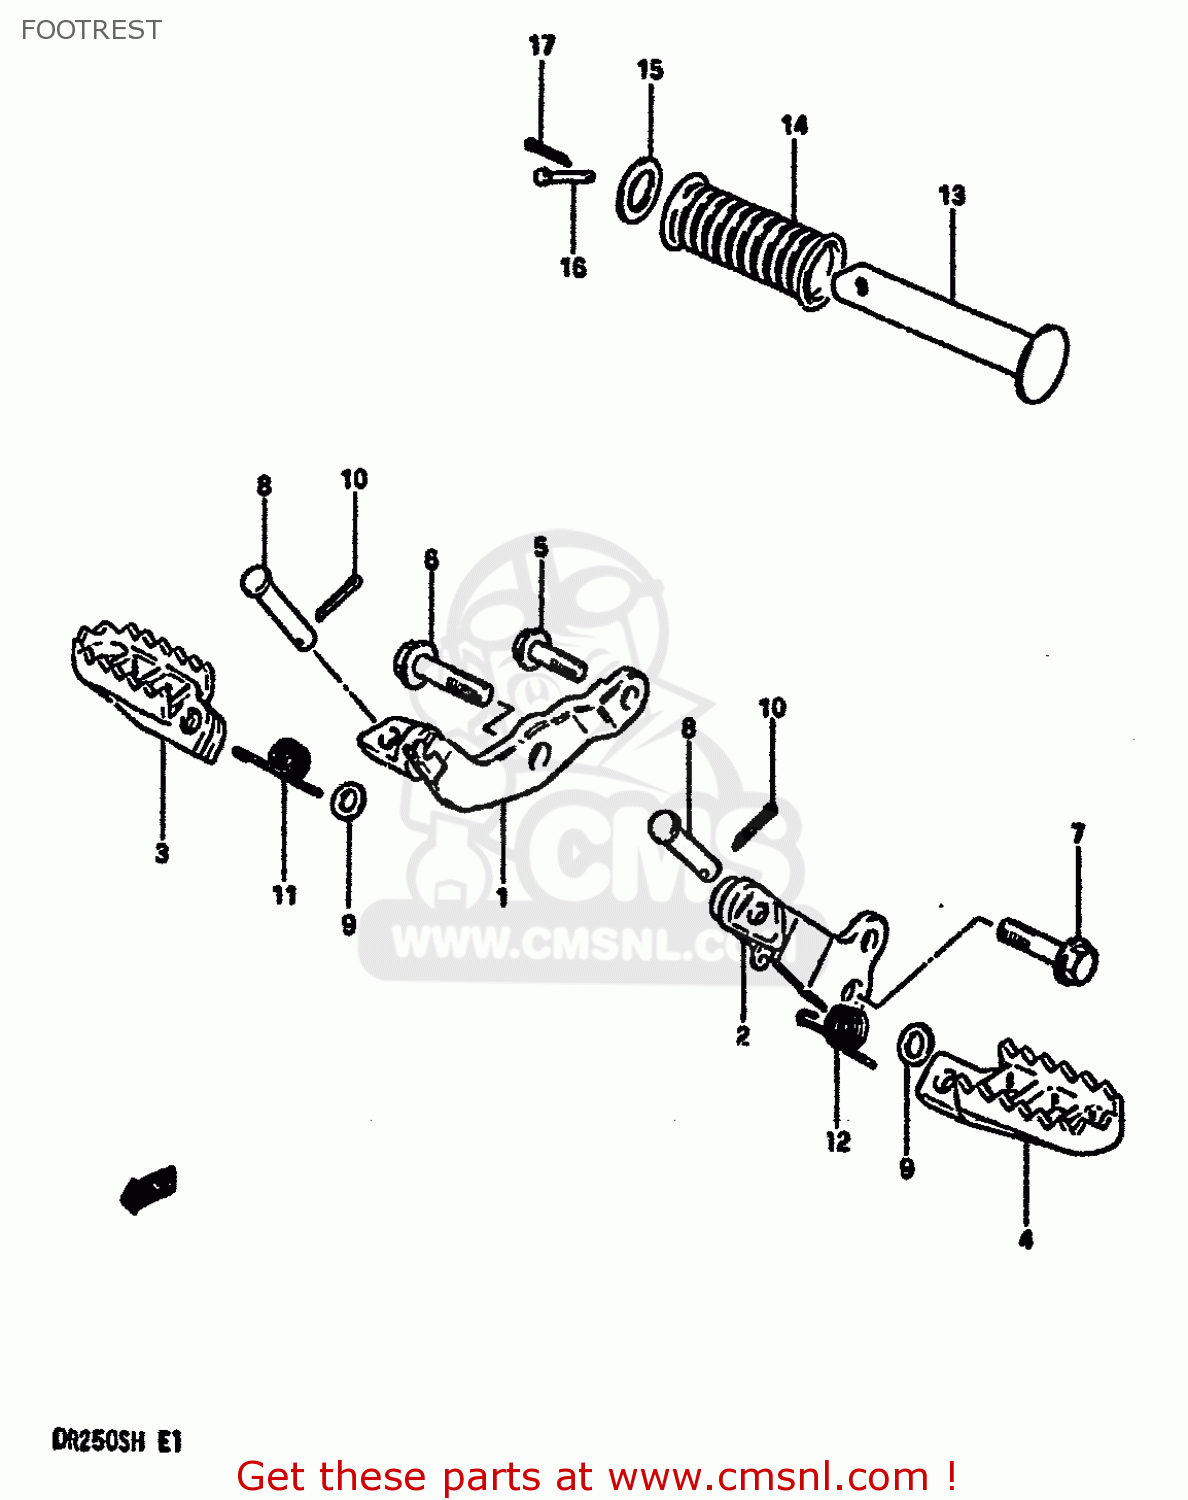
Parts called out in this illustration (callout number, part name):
1	BAR,FRONT FOOTREST
2	BAR,FRONT FOOTREST,LEFT
3	FOOTREST
4	FOOTREST
5	BOLT,LOWER
6	BOLT, RH
7	BOLT
8	PIN
9	WASHER
10	PIN 20X20
11	SPRING
12	SPRING
13	BAR,FOOTREST RUBBER
14	RUBBER,PILLION FOOTREST
15	WASHER (19.5X32X2)
16	PIN
17	PIN 20X20
